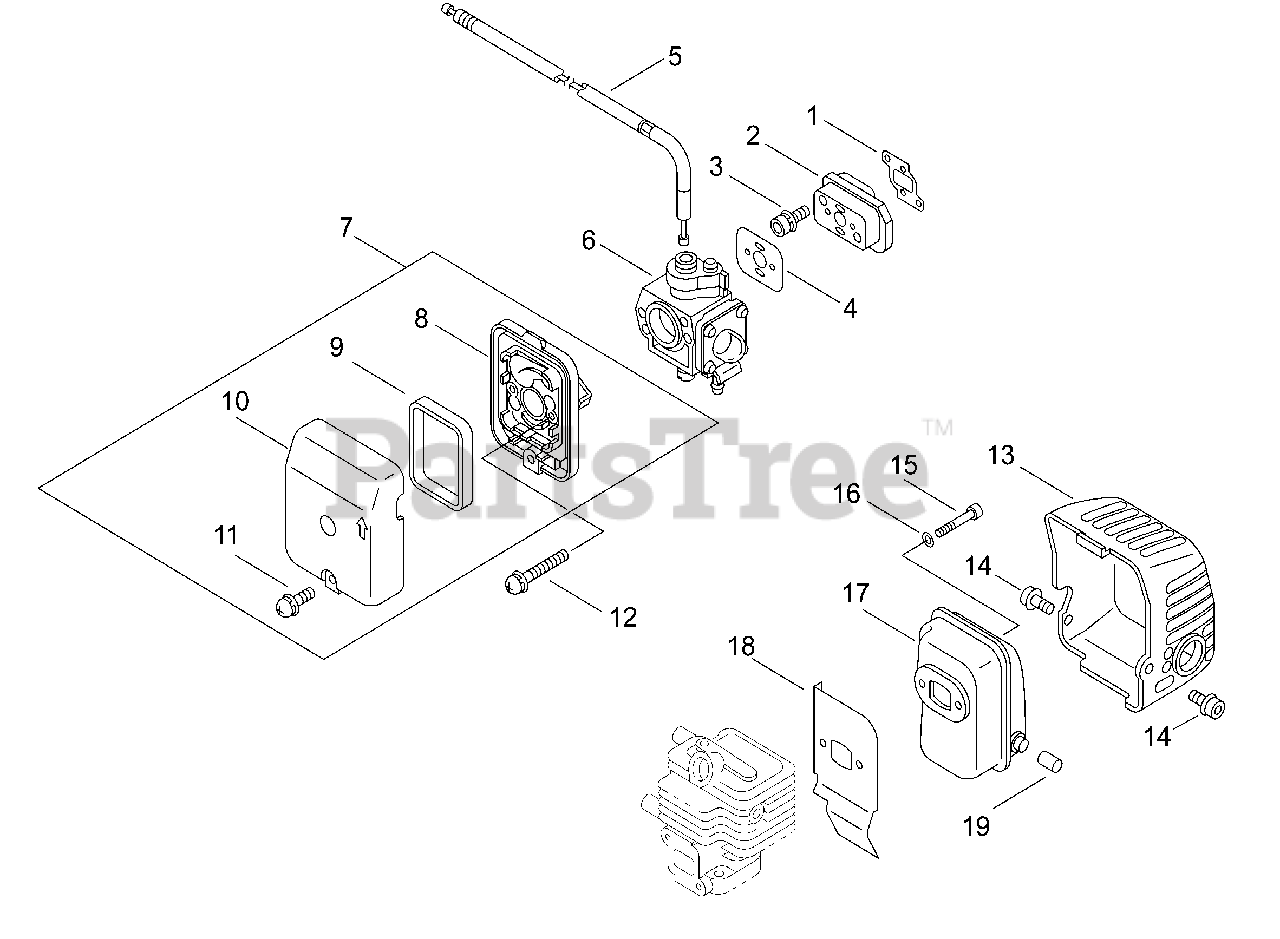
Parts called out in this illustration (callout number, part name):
1	GASKET, INTAKE
2	INSULATOR, INTAKE
3	BOLT 5×25
4	GASKET, INTAKE
5	CABLE, THROTTLE
6	CARBURETOR
7	FILTER ASSY, AIR
8	CASE, AIR FILTER
9	FILTER, AIR
10	COVER, AIR FILTER
11	SCREW 5×16
12	SCREW 5×50
13	COVER, MUFFLER
14	BOLT 5×8
15	BOLT 5×55
16	WASHER, FLAT 5.5×10×0.8
18	HEAT SHIELD, EXHAUST
19	PIPE, EXHAUST
